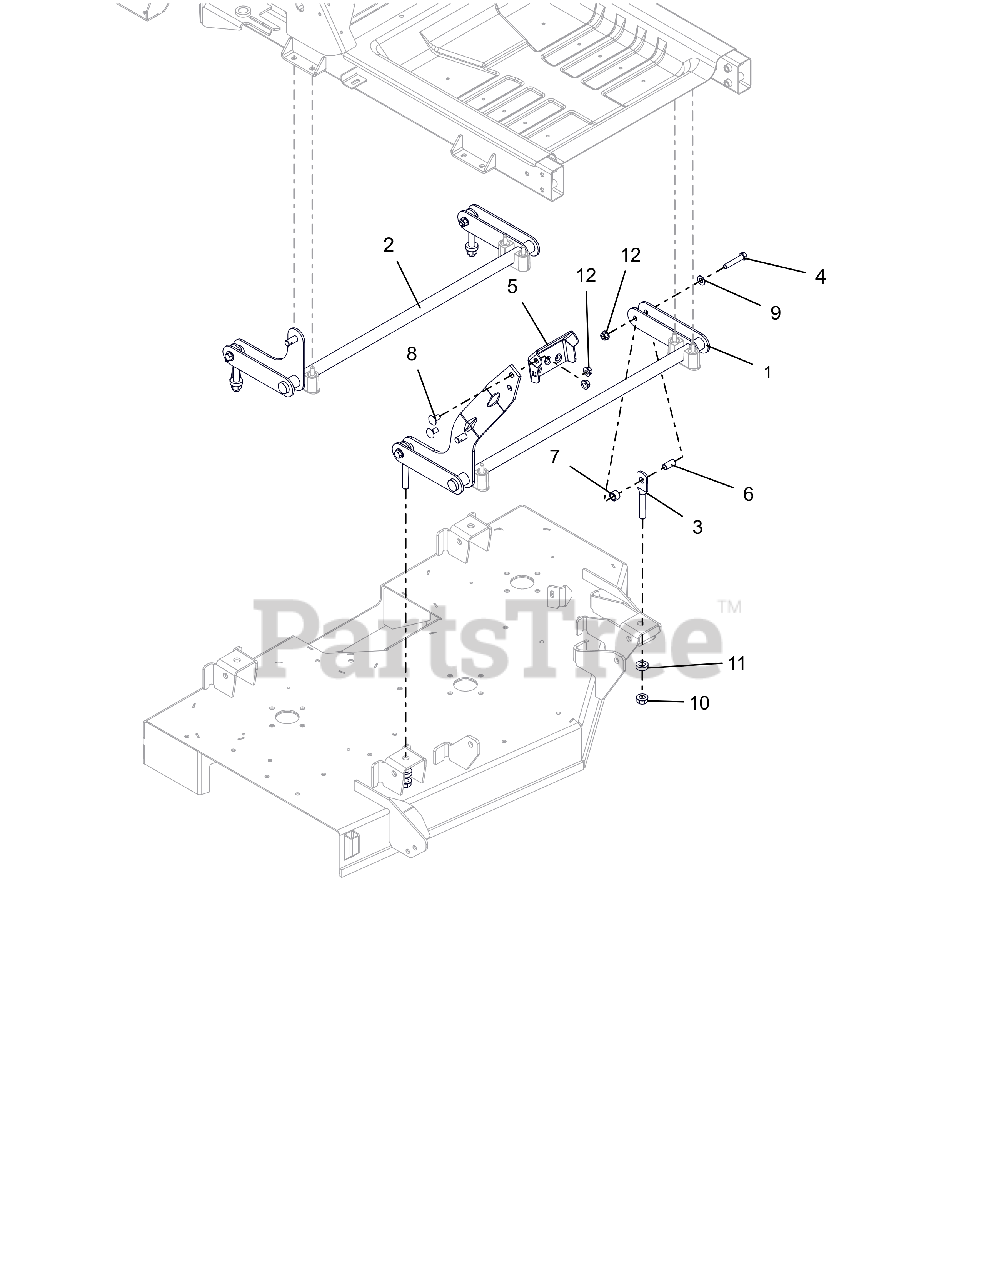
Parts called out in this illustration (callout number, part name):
1	WLDMT, FRONT DECK LIFT PIVOT
2	WLDMT, REAR DECK PIVOT
3	LINK, DECK (HOLE-SHORT)
4	BLT, HEX .38-16X2.00 G8 ZCC
5	PEDAL, DECK LIFT (BOLT ON)
6	BSHG-SLV .385X.500X1.045
7	BSHG-SLV .510X.751X.475
8	BLT,RHSN .38-16X.75 G5 BFP
9	WSHR,FLT .406X.812X.065 ZCC
10	NUT-LK-CTR-FLG .500-13 GG ZCC
11	WASHER, RUBBER
12	NUT-LK-CTR-FLG .375-16 GF ZCC
